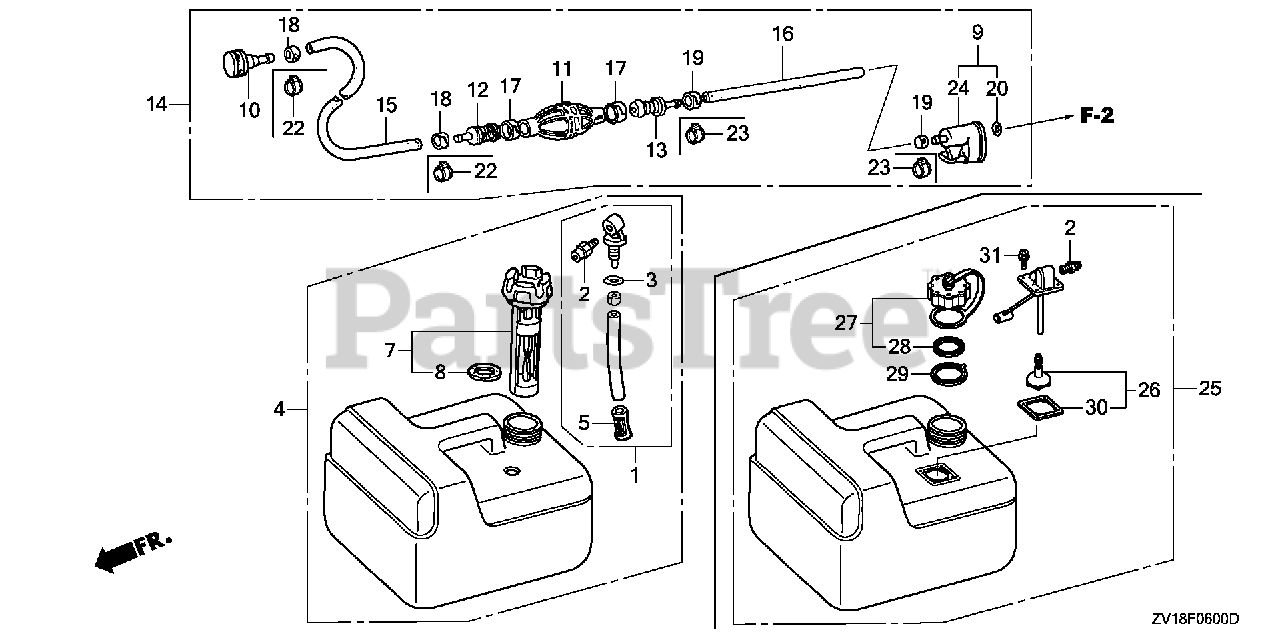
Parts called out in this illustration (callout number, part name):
1	JOINT ASSY., FUEL
2	FITTING, QUICK DISCONNECT Use from Frame SN 1205705.
3	O-RING Use from Frame SN 1300962.
4	TANK ASSY., FUEL
4	TANK, FUEL (12L)
5	FILTER, FUEL
7	CAP, FUEL FILLER
8	GASKET, FUEL CAP
9	CONNECTOR, FUEL *NH1* (BLACK)
9	CONNECTOR, FUEL *NH282MU* (OYSTER SILVER METALLIC-U)
10	CONNECTOR, FUEL (CONNECTOR TYPE)
11	BULB, PRIMER
12	VALVE, IN.
13	VALVE, OUTLET
14	TUBE, FUEL *NH1* (BLACK)
14	TUBE ASSY., FUEL TANK
14	TUBE, FUEL *NH282MU* (OYSTER SILVER METALLIC-U)
15	TUBE, FUEL LONG (7.3X2000) (CONNECTOR TYPE)
15	TUBE, FUEL LONG (7.3X2000)
16	TUBE, FUEL SHORT
16	TUBE, FUEL SHORT (6.3X500)
17	BAND, TUBE CLIP (20MM)
18	BAND, TUBE CLIP (12.5MM)
19	BAND, TUBE CLIP (11MM)
20	O-RING (5.5MM)
22	CLAMP, FUEL TUBE (CONNECTOR TYPE)
23	CLAMP, FUEL TUBE
24	CONNECTOR ASSY., FUEL (A)
